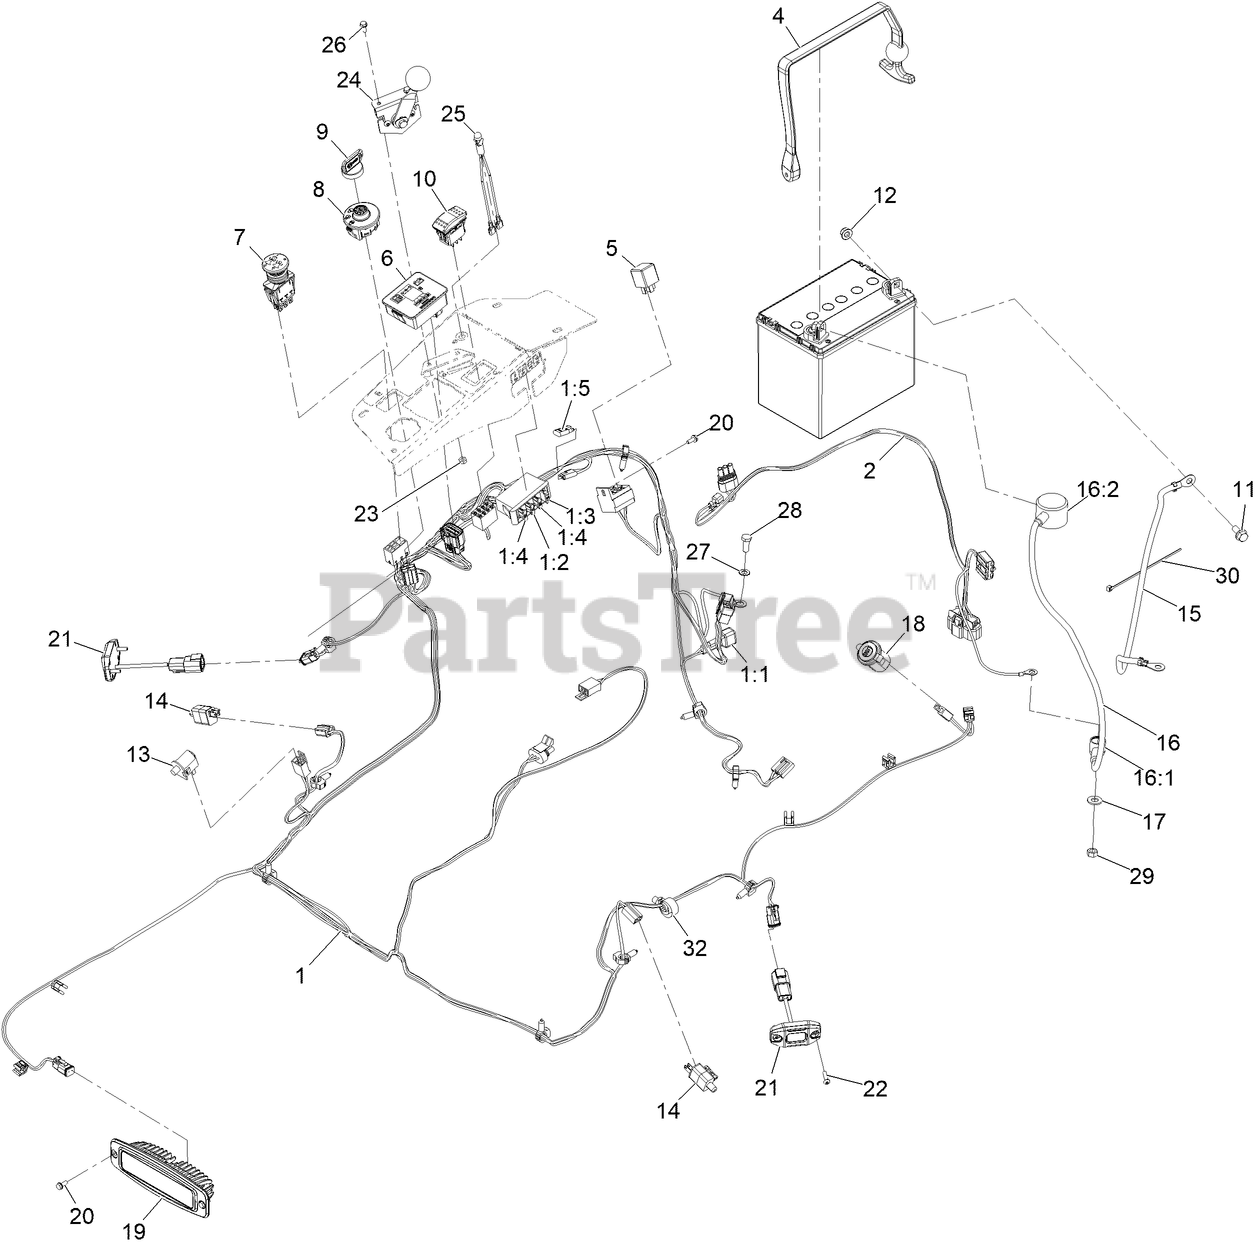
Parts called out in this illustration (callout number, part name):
1	HARNESS-MAIN LRX CARB
1:2	FUSE-BLADE, 10 AMP
1:3	FUSE-BLADE, 15 AMP
1:4	FUSE-BLADE, 25 AMP
1:5	CAP-PLUG
2	Harness-Adapter EFI, Etc
4	Strap-Bungee
6	FUEL/HOUR METER ASM
7	SWITCH, PTO 10A
8	SWITCH-IGNITION
9	KEY-IGNITION
11	SCREW-HHF
12	NUT-HF, NI
13	SWITCH-BAIL
15	CABLE-BATTERY, NEGATIVE
16	CABLE-BATTERY, POSITIVE
16:1	INSULATOR-SOLENOID
16:2	INSULATOR-BATTERY
17	WASHER-FLAT
18	PORT-POWER, USB
19	MOUNT-FLUSH, LIGHT
20	Screw-HWH
21	LIGHT-ROCK
22	Screw-HSBH
23	NUT-LOCK, NI
24	THROTTLE CONTROLLER-ETC
25	INDICATOR-LED, RED
26	SCREW-HWH
27	WASHER-LOCK
28	SCREW-HH
29	NUT-HEX
30	TIE-CABLE
32	CLIP-TIE
